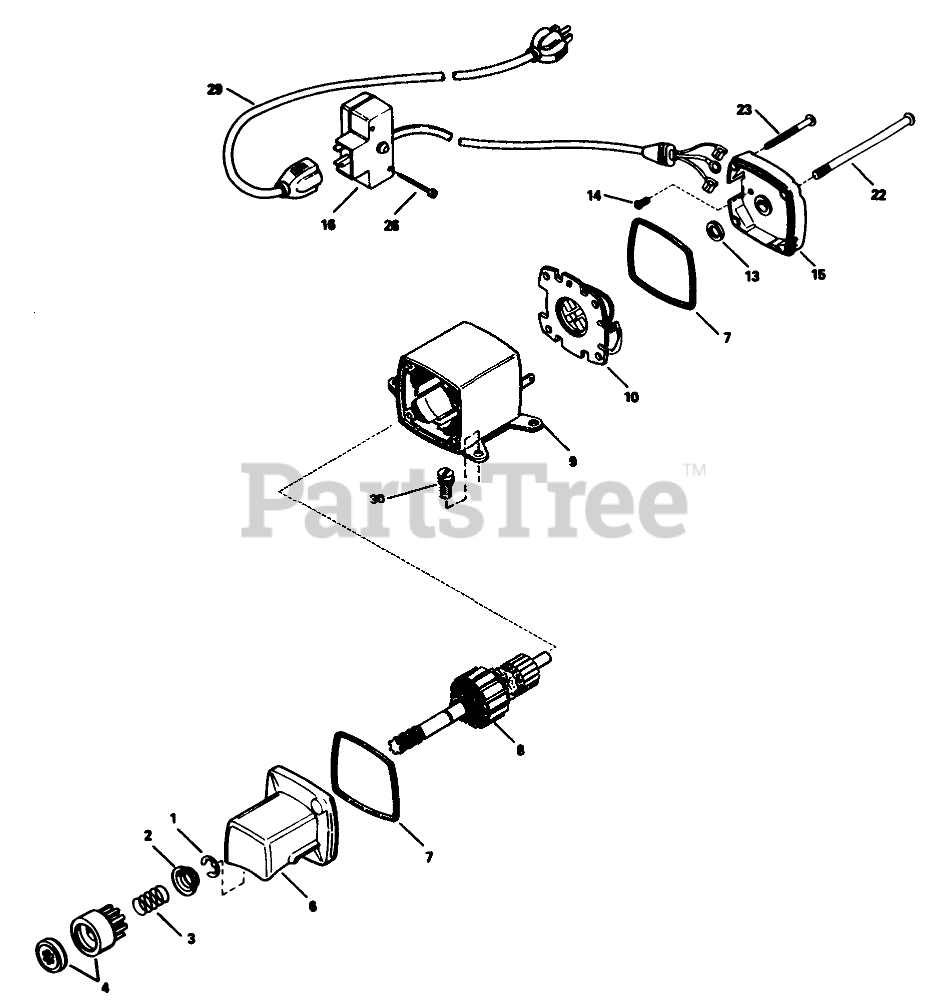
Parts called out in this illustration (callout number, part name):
1	Retainer-Ring
2	Retainer-Spring
3	Spring-Anti Drift
4	Nut & Gear
6	Cap Assy.-Drive End (Incl. Ref. #7)
8	Armature
9	Housing Assembly
10	Card ASM
13	Washer-Thrust
14	Screw-Ground
15	Cap Assy.-Commutator End (Incl. Ref. #7)
16	Switch Box ASM
22	Bolt-Case
23	Screw-Ground
29	Cord-Extension
30	Screw (T-30, 1/4-20 x 23/32)
